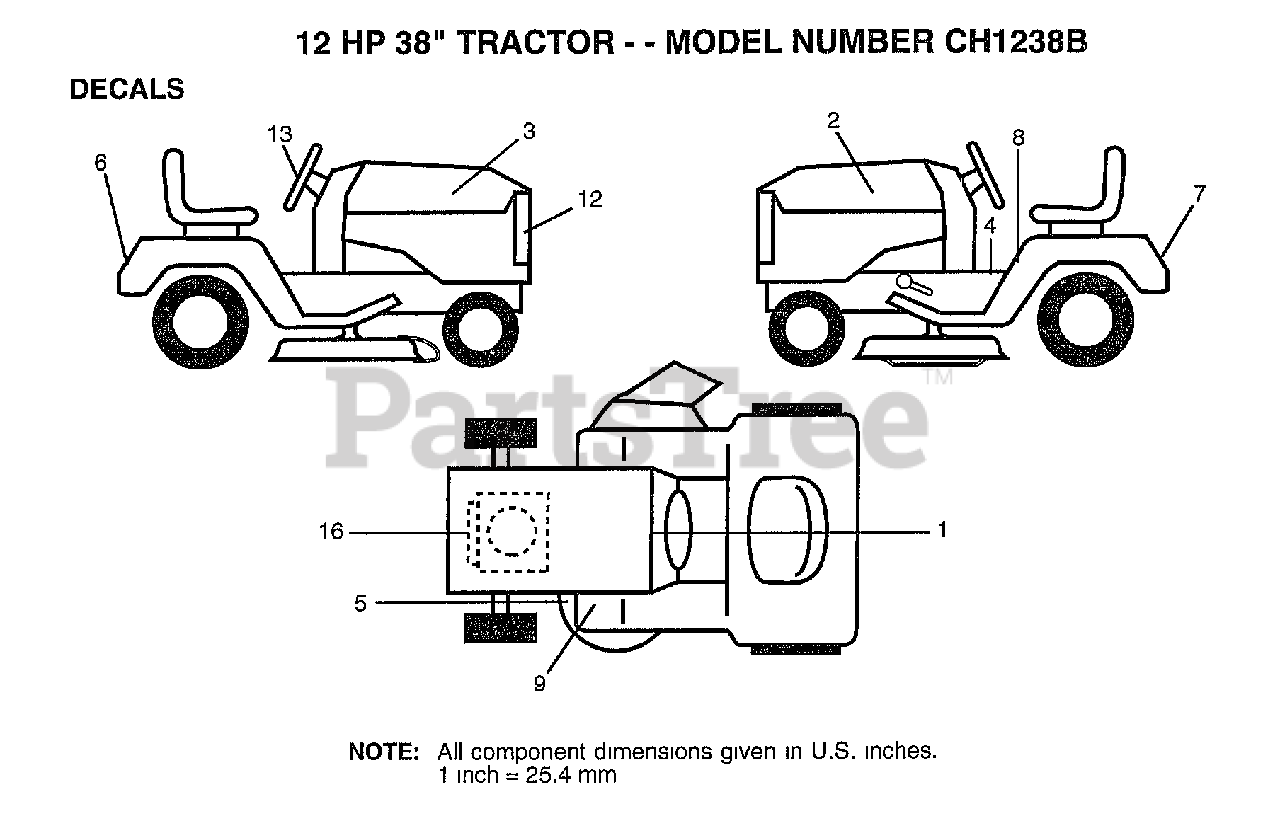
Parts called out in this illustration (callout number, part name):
1	DECAL.DASH.INSTR.
2	DECAL.HOOD.LH
3	DECAL.HOOD.RH
4	DECAL BRAK PARK
5	DECAL.V.BELT
6	DECAL.FENDER
8	DECAL
13	DECAL.INSRT.STRG
14	DECAL
16	DECAL.ENG.271967
